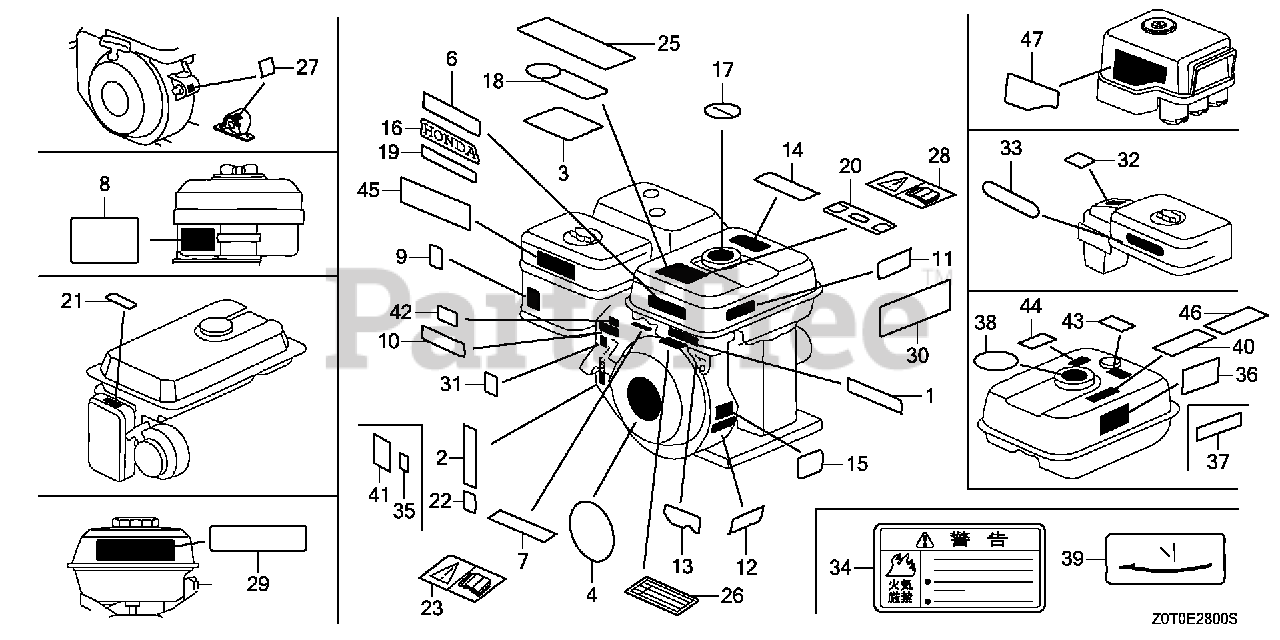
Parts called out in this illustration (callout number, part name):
4	EMBLEM (GX160)
6	LABEL, CAUTION
7	LABEL, CAUTION
9	MARK, CHOKE
